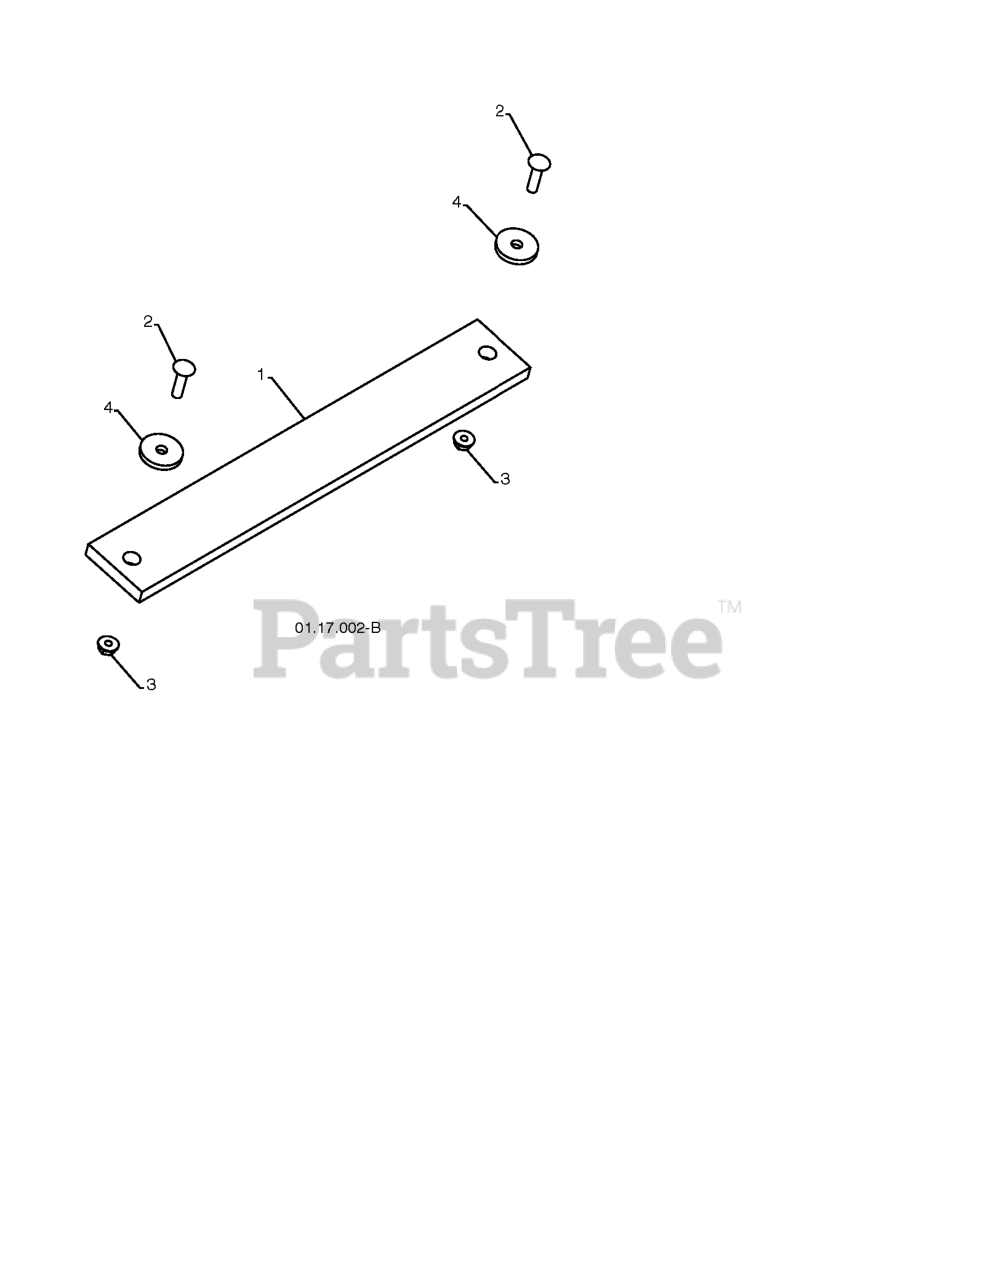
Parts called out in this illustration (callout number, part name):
1	WEIGHT,AUGER HOUSING 27 (2 2MC
2	BOLT.CARRIAGE.5/16-18
3	NUT.LOCK.5/16-18
4	WASHER.FLAT.34X1.38X22
